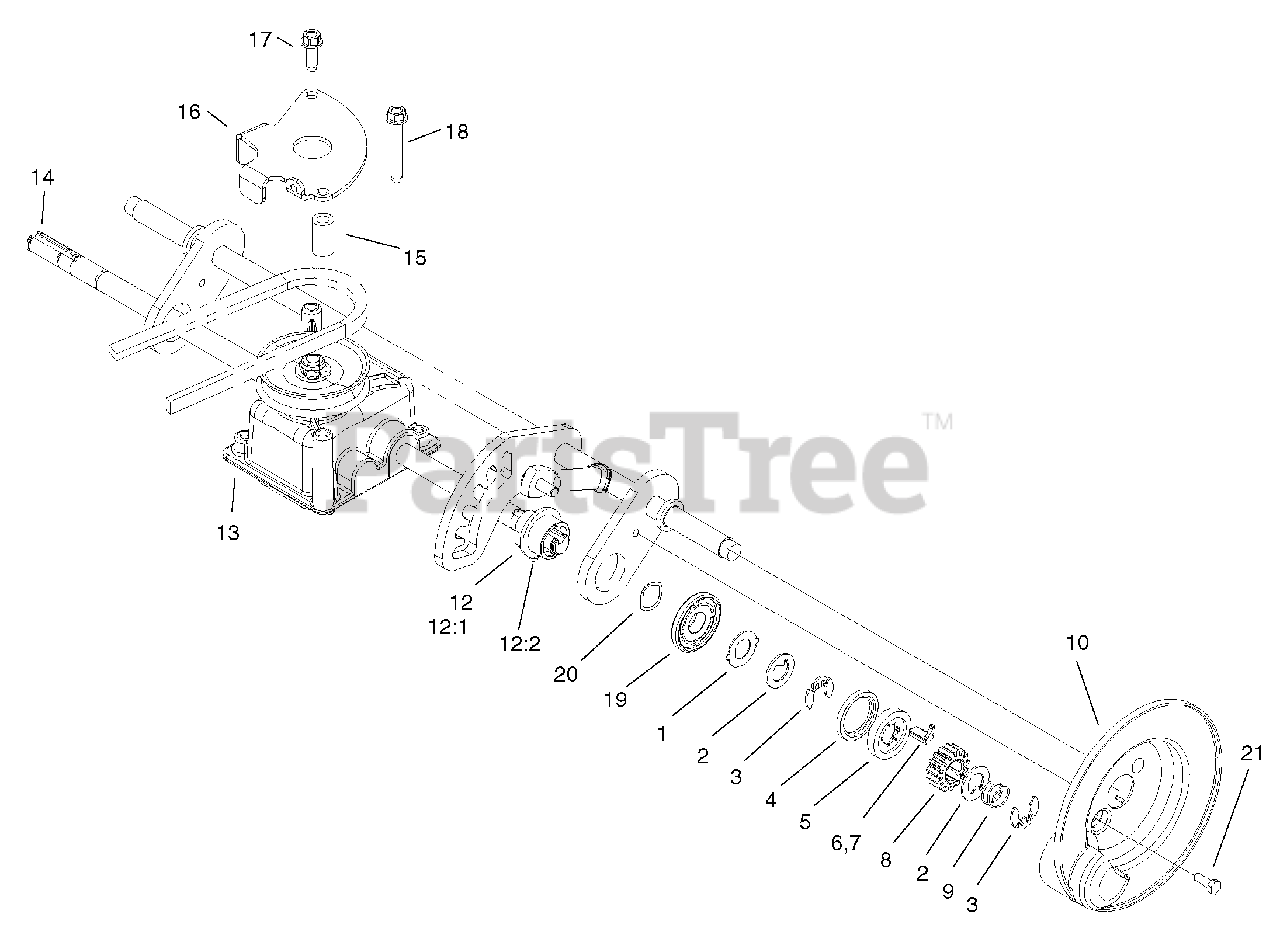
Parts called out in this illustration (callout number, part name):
1	Washer-Arm, Pivot (only on: 10929)
2	Washer-Thrust, Keyed (only on: 10929)
3	Ring-Klip (only on: 10929)
3	Ring-Klip (only on: 10924)
4	Ring-Friction (only on: 10929)
5	Washer-Clutch (only on: 10929)
6	Key-Rocking, RH (only on: 10929)
7	Key-Rocking, LH (only on: 10929)
8	Gear-Pinion (only on: 10929)
9	Spring-Compression (only on: 10929)
10	Cover-Gear
12	Bushing ASM
12:1	Bushing-Drive Shaft
12:2	Fitting-Zerk
13	Gear Case ASM (only on: 10929)
14	Shaft-Pivot (only on: 10924)
15	Bushing-Plate, Actuator (only on: 10929)
16	Guide-Transmission (only on: 10929)
17	Screw-Tapping (only on: 10929)
18	Screw-HWHTF (only on: 10929)
19	Retainer-Ring (only on: 10929)
20	Washer-Wave (only on: 10929)
21	Screw-Taptite
